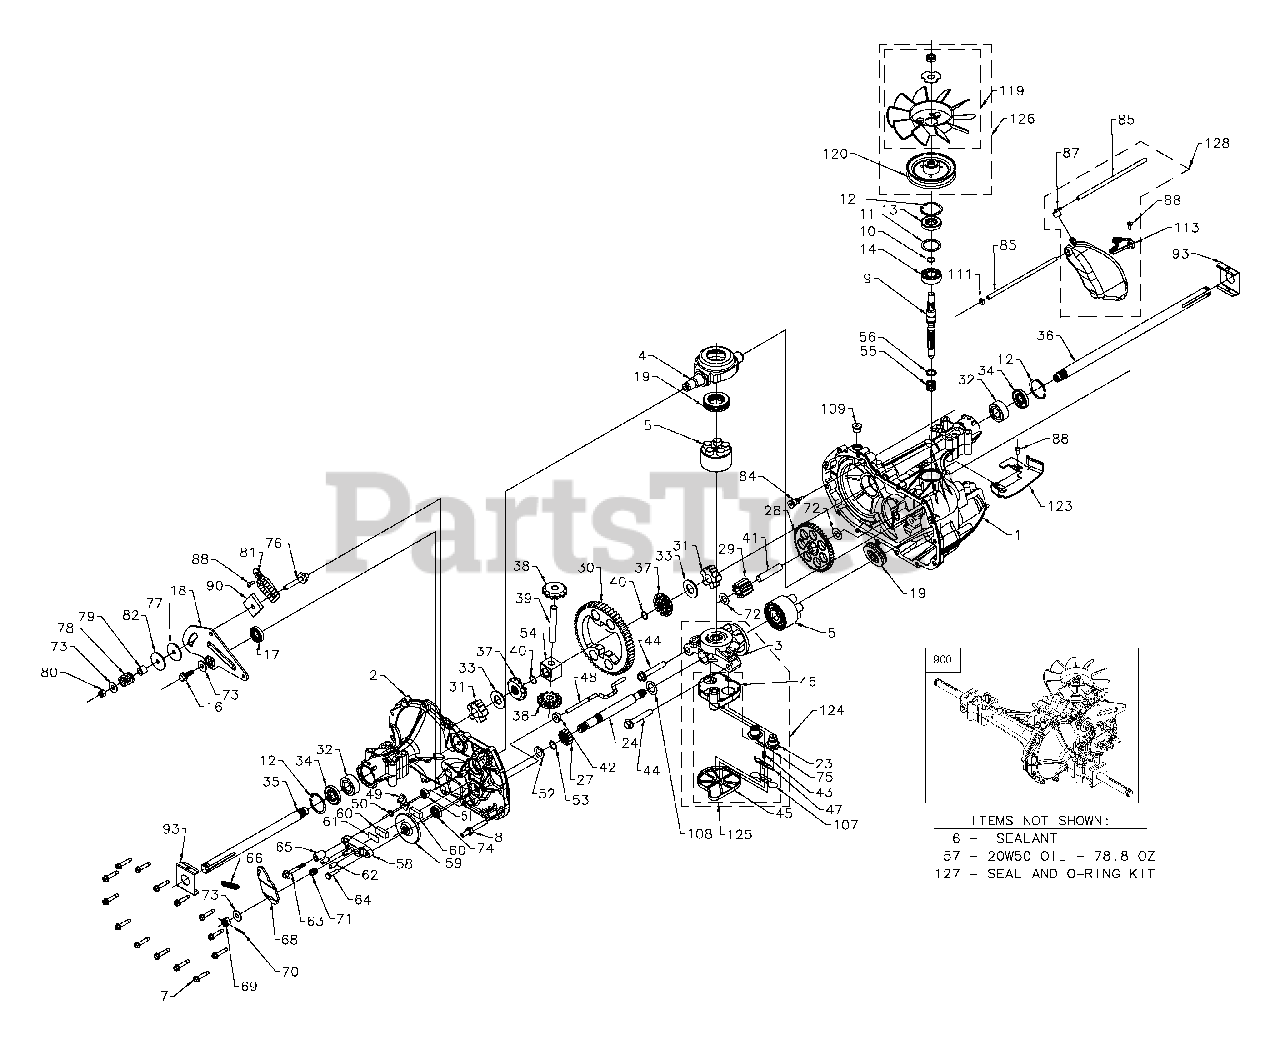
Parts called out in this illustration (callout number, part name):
1	Kit, Main Housing
1	Main Housing, Machined
2	Kit, Side Housing
2	Side Housing, Machined
3	Kit, Center Section Center Section, Machined
4	Swashplate, Trunnion Machined
5	Kit, Cylinder Block
5	(1000) Block - Cylinder
5	Piston
5	Spring, Compression Washer Thrust
6	Sealant Tube
7	Hex flange Screw 1/4-20 X 1.25
8	Stud, 5/16-24 Hex Double End
9	Shaft, Input
10	Retaining Ring
11	Spacer
12	Retaining Ring
13	Seal, Lip.67 X 1.58 X.276
14	Bearing, Ball 6203 (BDR)
16	Hex Flange Head Screw 1/4-20 X 1.25
17	Seal, Lip 18 X 32 X 7
18	Arm, Control
19	Bearing, Thrust (10cc)
23	Shock Valve Assembly 270 Bar
24	Shaft Motor
27	Gear, Pinion, 12T
28	Gear 1 OT / 49T
29	Gear, 1 OT Jackshaft
30	60t Bullgear
31	Sleeve Bearing .75 X 1.75 X.625
32	Sleeve Bearing (Outboard) .75 X 1.575 X.625
33	Washer
34	Lip Seal, Axle Shaft
35	Shaft, Axle (Keyed, R.h.)
36	Shaft, Axle (Keyed, L.h.)
37	Gear, Steel Miter 12T (Splined)
38	Gear, Steel Miter 12T
39	Differential Shaft (310-0750)
40	Retaining Ring
41	Pin, Jackshaft
42	Magnet, Ring
43	Spring, Bypass
44	Bolt 3/8-24 X 2-1/2
46	Base, Filter
47	Actuator, Bypass
48	Rod, Bypass Actuator
49	Arm, Bypass
50	Retaining Ring.25 External
51	Seal, Lip .741 X.25 X.25
52	Washer, Flat 0.050" (210-1000)
53	Retaining Ring
54	Bearing, Center Block
55	Spring, Helical Compression
56	Washer, Block Thrust
57	Oil
58	Kit, Brake Yoke
59	Rotor, Brake
60	Brake Puck
61	Brake Puck Plate
62	Pin, Brake Actuating
63	Hfhcs 1/4-20 X 2 W/patch, Special Flange
64	Bolt, Nylok
65	Spacer, Brake Torsion Spring
66	Spring, Brake Arm Bias
68	Arm-brake, RH
69	Nut, Castle 5/16-24
70	Pin, Cotter 3/32x3/4
71	Brake Spring
72	Washer (310-0750)
73	Washer, Flat
74	Seal, Oil
75	Ass'y Check Plug
76	Bolt, Stud 5/16-24
77	Puck, Friction
78	Spring
79	Spacer
80	Nut, Nylon Insert Hex Lock 5/16-24
81	Wedge, Friction
82	Clip, Washer
84	Fitting, 5/16 X Sae 5/32 Tube
85	Hose, Expansion Tank
87	Cap, Barbed Vent
88	Bolt, Self Tapping (BDR)
90	Puck, Inner Wedge
93	Spring Clip, Housing
107	Deflector
108	Washer, Motor Shaft.71 ID X 1.150D X.03 Thick
109	Plug, Straight Thread 9/16-18
111	O-ring .7 X.301 ID
113	Bracket, Support Expansion Tank
119	Kit, Fan - Washer - Nut
119	Fan, 7 In
119	Hex Lock Nut 1/2-20 (Nylon Insert) Washer
120	Pulley
123	Belt Keeper
124	Center Section Filter Bypass Assembly
124	Center Section Base Filter W/ Poppet
124	Shock Valve Assembly
124	270 bar Check Plug Assembly, .027 Washer
124	Spring,
124	Bypass Actuator,
124	Bypass Deflector Bottom, Filter
125	Kit, Filter
125	Bottom, Filter Spring,
125	Bypass Actuator,
125	Bypass Deflector
125	Base, Filter W/ Poppet
126	Kit, Fan/pulley
126	Hex Jam 1/20-20 (Nylon Inser) Washer,
126	Fan, 7 In
126	Pulley
127	Kit, Seal
127	O-ring.07 X .301 ID
128	Kit, Expansion Tank
128	Tank,
128	Expansion Assembly Cap,
128	Barbed Vent Bolt,
128	Self Tapping 10-32 X 1/2 Bracket,
128	Support Expansion Tank Hose,
128	Expansion Tank
900	Transaxle
